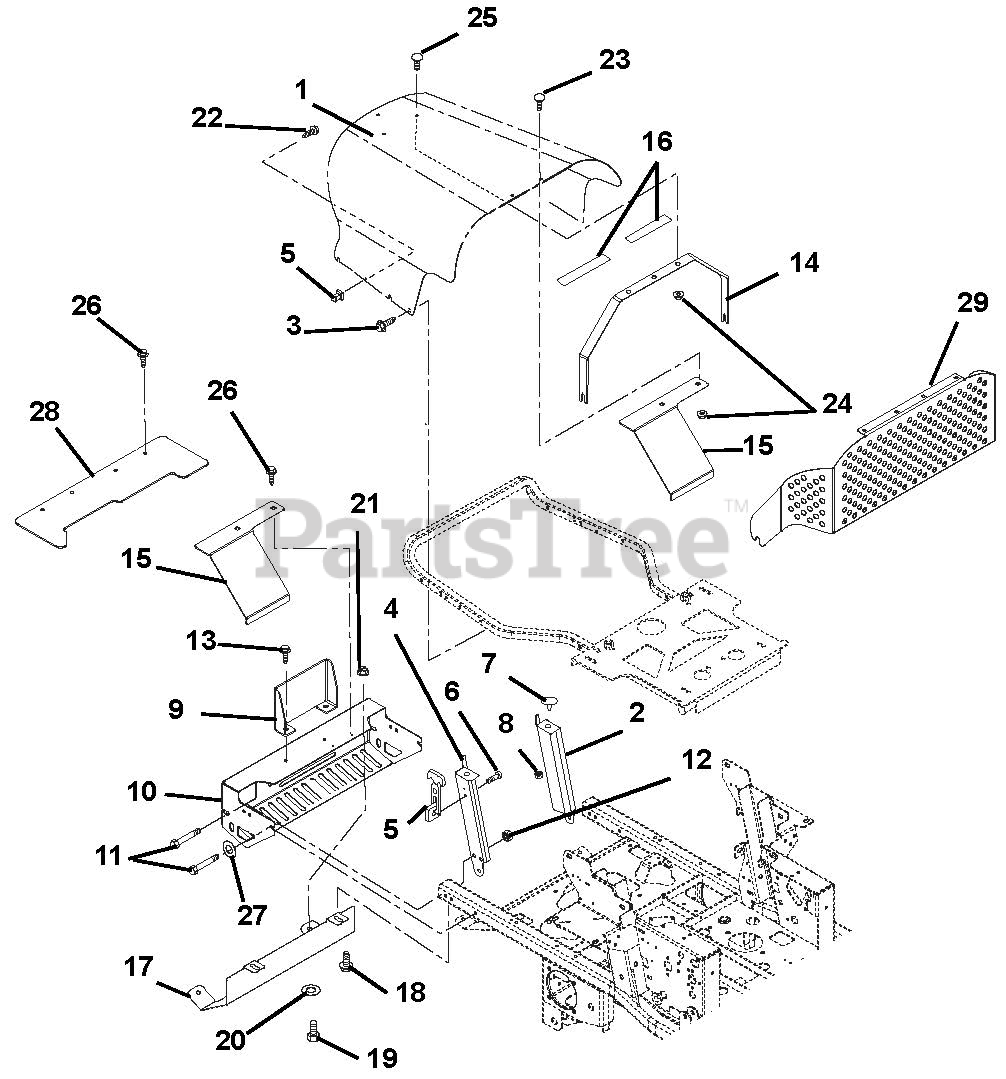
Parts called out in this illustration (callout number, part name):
1	Hood
2	Weldment, Hood Support, Left Hand
3	Screw, Tapping .38-16 x .75 Hex Washer Head
4	Weldment, Hood Support Right Hand
5	Latch, Rubber
6	Screw, Machine 10-24 x .50 Hex Washer Head
7	Button Bumper
8	Nut, Spin Lock-Flange .312-18
9	Guard, Muffler
10	Bumper, Rear
11	Bolt, Hex .38-16 x 2.75 Grade 5
12	Nut, Locking-Top-Flange .38-16
13	Screw, Tapping .38-16 x .75 Hex Washer Head
14	Hood Support
15	Guard
16	VHB Tape 4941F
17	Heat Shield
18	Screw, Tapping .38-16 x .50 Hex Washer Head Thread Rolling YWZ
19	Bolt, Hex .38-16 x .75 Grade 5
20	Washer, Flat-Steel .438 x1.00 x .083 YWZ
21	Nut, Locking-Top-Flange .38-16
22	Screw, Machine 10-24 x 1.50 Hex Washer Head
23	Bolt, Round Head Square Neck .25-20 x .50 Grade 5
24	Nut, Locking Top Flange .25-20
25	Bolt, Round Head Square Neck .25-20 x .75 Grade 5
26	Screw, Tapping .25-20 x .50 Hex Washer Head Thread
27	Washer, Flat Steel .406 x .812 x .065
28	Shield, Heat
29	Plenum, Hood
